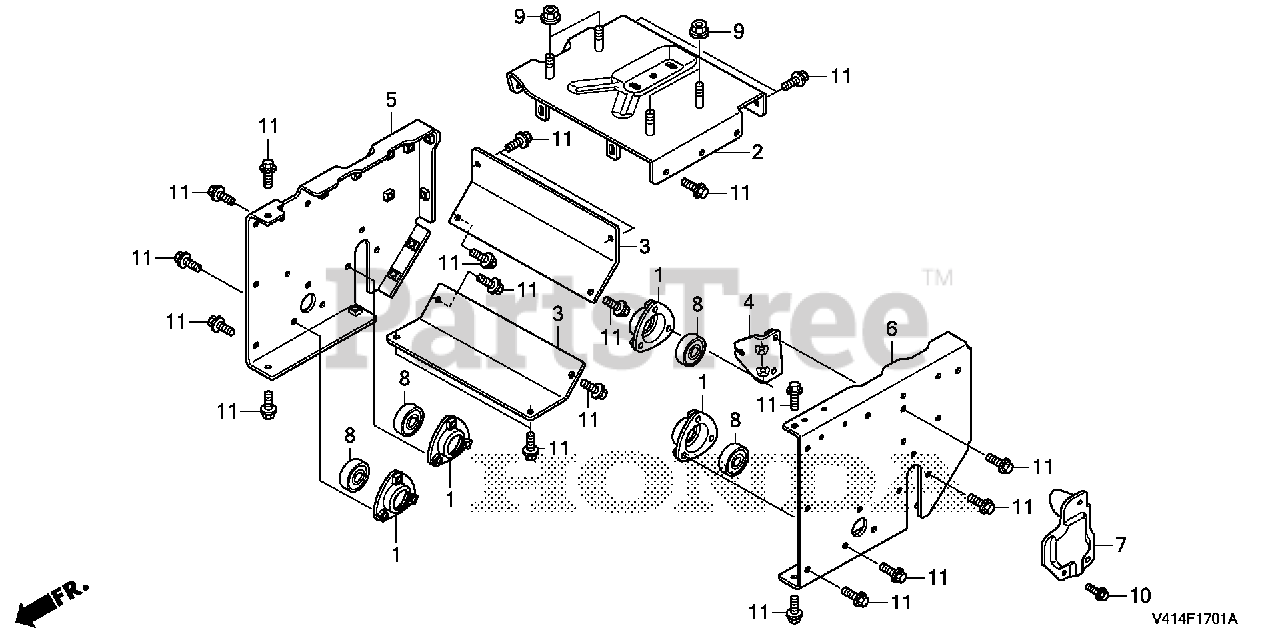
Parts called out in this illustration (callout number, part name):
1	HOLDER, BEARING
2	BED, ENGINE
3	STAY A, ENGINE BED
4	STAY, CHANGE CABLE
5	STAY, R. ENGINE BED
6	STAY, L. ENGINE BED
7	BRACKET, MOTOR COVER
8	BEARING, RADIAL BALL (6203-19.05)
9	NUT, FLANGE (10MM)
10	BOLT, FLANGE (6X12)
11	BOLT, FLANGE (8X16)
